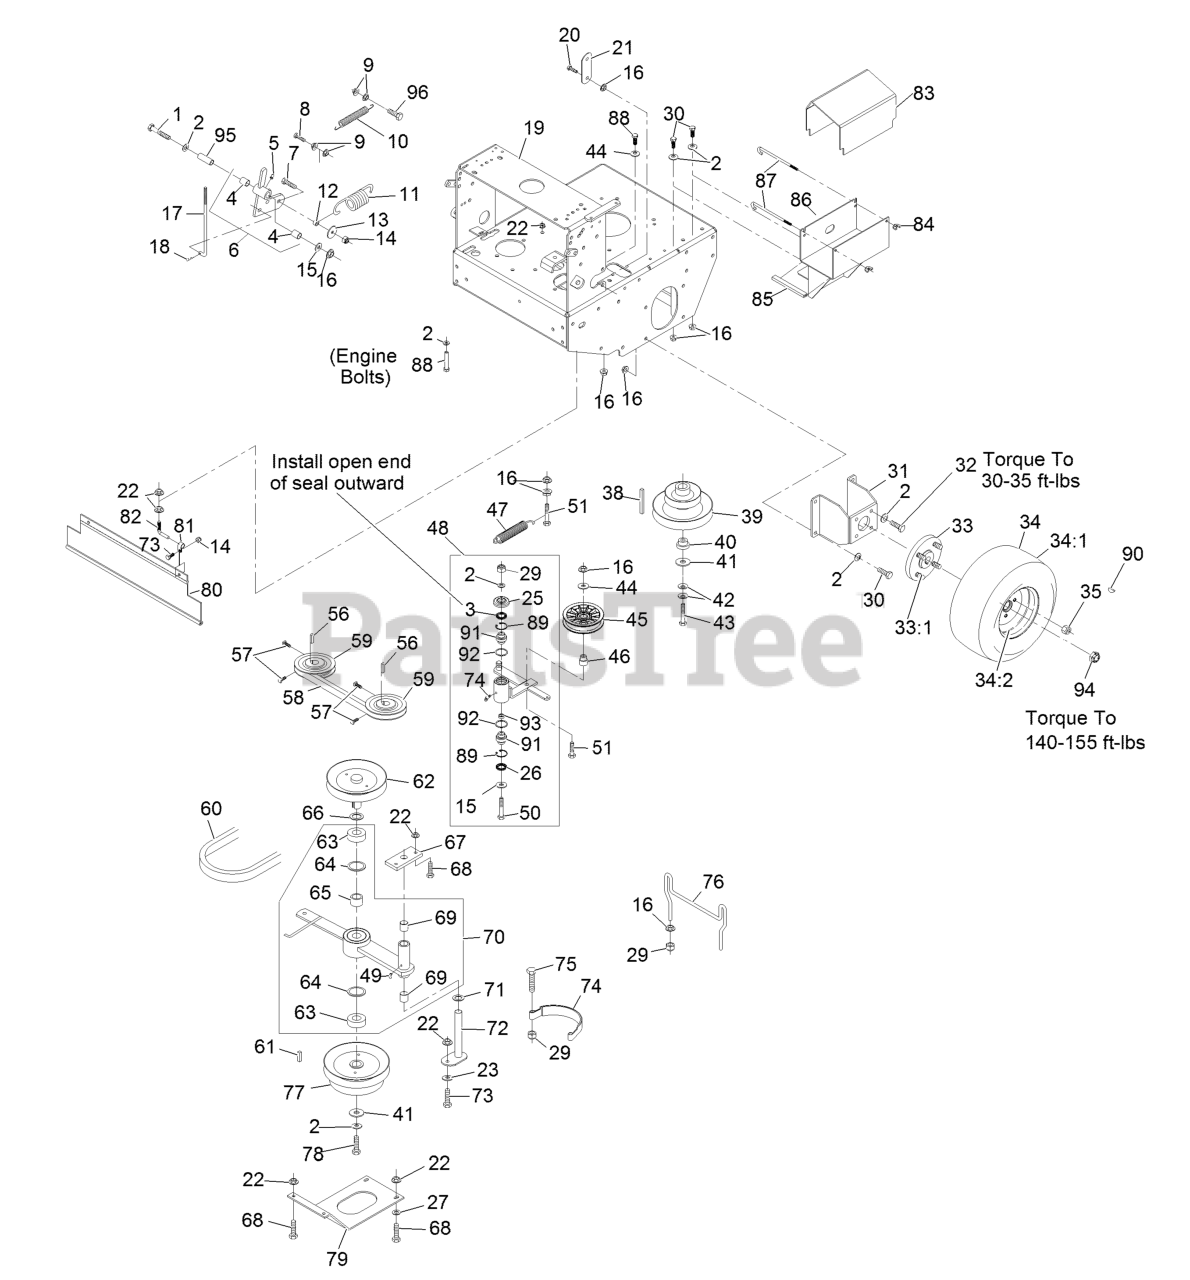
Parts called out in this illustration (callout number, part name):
1	SCREW-HH
2	WASHER-BELLEVILLE
3	SEAL-LIP, SINGLE
4	SLEEVE-BEARING
5	FITTING-GREASE
6	ASM,PIVOT W/BUSHINGS
7	SCREW-HH
8	SCREW-HH
10	SPRING,EXTENSION
11	SPRING,EXTENSION
12	SPACER,CLUTCH ANCHOR
14	NUT-LOCK, NI
15	WASHER-FLAT
16	NUT-HHF, WHIZ
17	LINKAGE,LOWER
18	PIN-COTTER
19	KIT, TTS ENG DECK
20	SCREW-HH
21	ARM-LIFT, DECK
23	WASHER-SPRING
25	GUARD-TOP
26	SEAL-LIP, DOUBLE
27	WASHER-FLAT
29	NUT-LOCK, NI
30	SCREW-HH
31	WLD,MOTOR MOUNT 48&52
32	SCREW-HH
33	WHEEL HUB ASM
33:1	STUD-WHEEL
34	WHEEL AND TIRE ASM
34:1	TIRE-TURFMASTER
34:2	RIM-WHEEL
35	NUT-LUG
38	KEY,MACH 1/4X1/4X2-5/8
39	SHEAVE, DRIVE
40	BUSHING,CLUTCH KEEPER
42	WASHER-SPRING
43	SCREW-HH
44	WASHER-FLAT
45	PULLEY-IDLER, FLAT
46	BUSHING-IDLER
48	KIT,PUMP IDLER ARM TTHP
49	FITTING-GREASE
50	SCREW-HH
51	SCREW-HH
57	SCREW-SET, SQH
58	BELT,COG A 50.55
59	SHEAVE ASM
60	BELT,B-38.0
62	SHEAVE, W/ SHAFT
63	BEARING,CLUTCH SHAFT
64	RING-SNAP
65	SPACER,CLUTCH BEARING
66	WASHER-SPACER
67	PLATE-CLUTCH PIVOT
68	SCREW-HH
69	SLEEVE,BEARING
70	ASM,CLUTCH ARM W/BEARING
71	WASHER-SPACER
72	WLD,PIN PIVOT
73	SCREW-HH
74	BAND,BRAKE BLADE
75	SCREW-HH
76	GUIDE,BELT (PLTD)
77	SHEAVE,6.75 W/DRUM
78	SCRW,CAP HH
79	PLATE-GUARD
80	SHIELD-DRAG
81	CLIP-LOOM
82	MOUNT,DRAG SHIELD
83	COVER,BATTERY W/DECAL
84	WINGNUT
85	TRIM-LOK
86	ASM,BATTERY STAND W/TRIM
87	BOLT - HOLD DOWN
88	SCREW-HH
89	RING-SNAP
90	KEY-WOODRUFF
91	BEARING-SPHERICAL
94	NUT-LOCK
95	BUSHING
96	SCREW-HH
